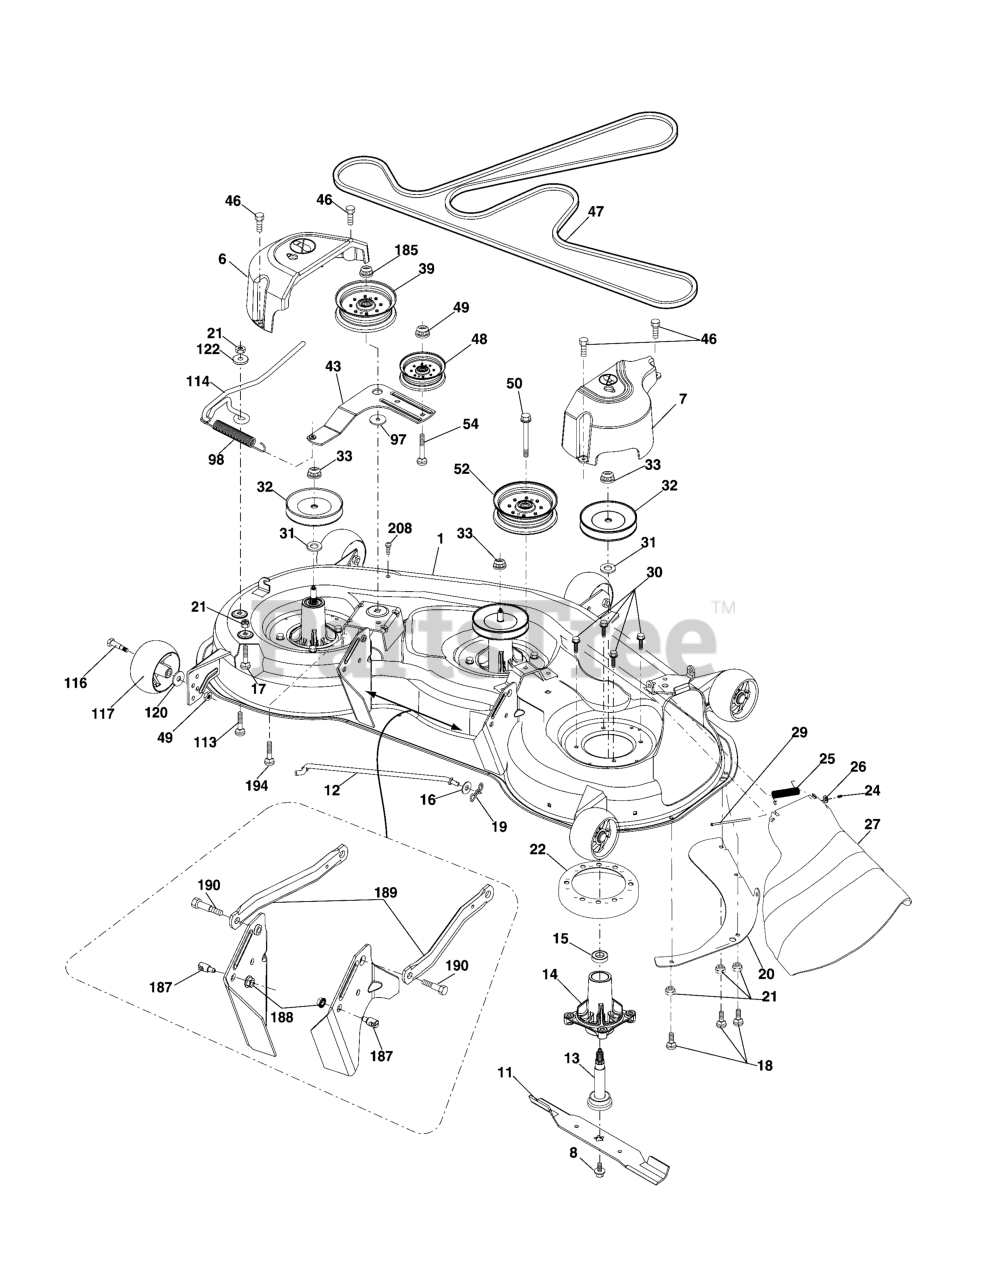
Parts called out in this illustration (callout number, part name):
1	Deck Weldment Mower
6	Cover Mandrel LH
7	Cover Mandrel RH
8	Bolt/Washer Asm. 7/16-20
11	Blade High Lift
12	Rod Anti-Sway
13	Shaft Asm. w/Lower Bearing
14	Housing, Mandrel
15	Bearing, Ball, Mandrel
16	Washer 13/32 x 13/16 x 12 Ga.
17	Bolt 5/16-18 x 5/8
18	Bolt RdHd 5/16-18 unc x 5/8
19	Pin Cotter 5/16 Bow Tie Lock
20	Baffle Vortex
21	Nut, Crownlock 5/16-18 unc
22	Mandrel Deck Stripper
24	Cap Sleeve
25	Spring, Torsion
26	Nut, Push
27	Deflector Shield
29	Rod, Hinge
30	Screw, Thdroll Washer Head
31	Washer, Spacer Mower Vented
32	Pulley, Mandrel
33	Nut, Flg. Top Lock
39	Pulley, Idler
43	Arm, Idler
46	Screw, Thdroll. 1/4-20 x 5/8
47	Belt Deck Drive
48	Pulley Idler Primary
49	Nut, Lock Flg. 3/8-16 unc
50	Screw 3/8-16 x 2-1/4
52	Pulley Idler Clutching
54	Bolt Carr SH 3/8-16 x 1-1/2 Gr. 5
97	Washer Hardened
98	Spring Drive
113	Bolt Rdhd Sqnk 5/16-18 x 3/4
114	Rod Tension Relief
116	Bolt, Shoulder
117	Gauge Wheel
120	Washer 13/32 x 1-1/4 x 12 Ga.
122	Bushing Tension Relief
185	Nut Lock Flange 7/16-14 Gr. 5
187	Stud Fastener w/"D" Anti-Rotation
188	Nut Lock Hex Flange 5/16-18
189	Arm Susp. Mower Rear
190	Bolt Shoulder
194	Bolt Carr Sqnk 7/16-24 x 2
208	Screw 3/8-16 x 1/2
